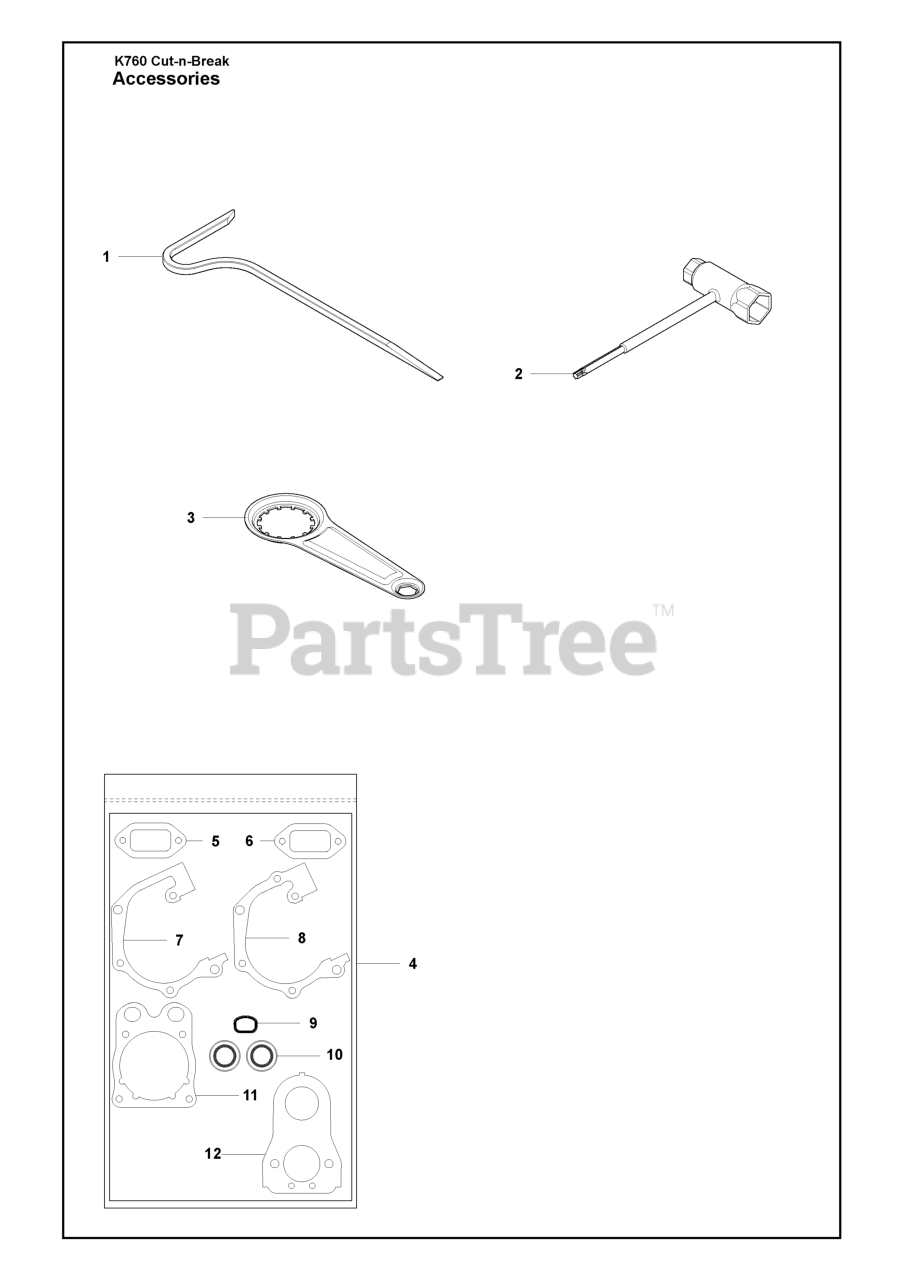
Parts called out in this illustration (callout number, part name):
1	Tool
4	GASKET KIT
6	GASKET
10	SEALING RING
12	RP GASKET CARBURETOR
